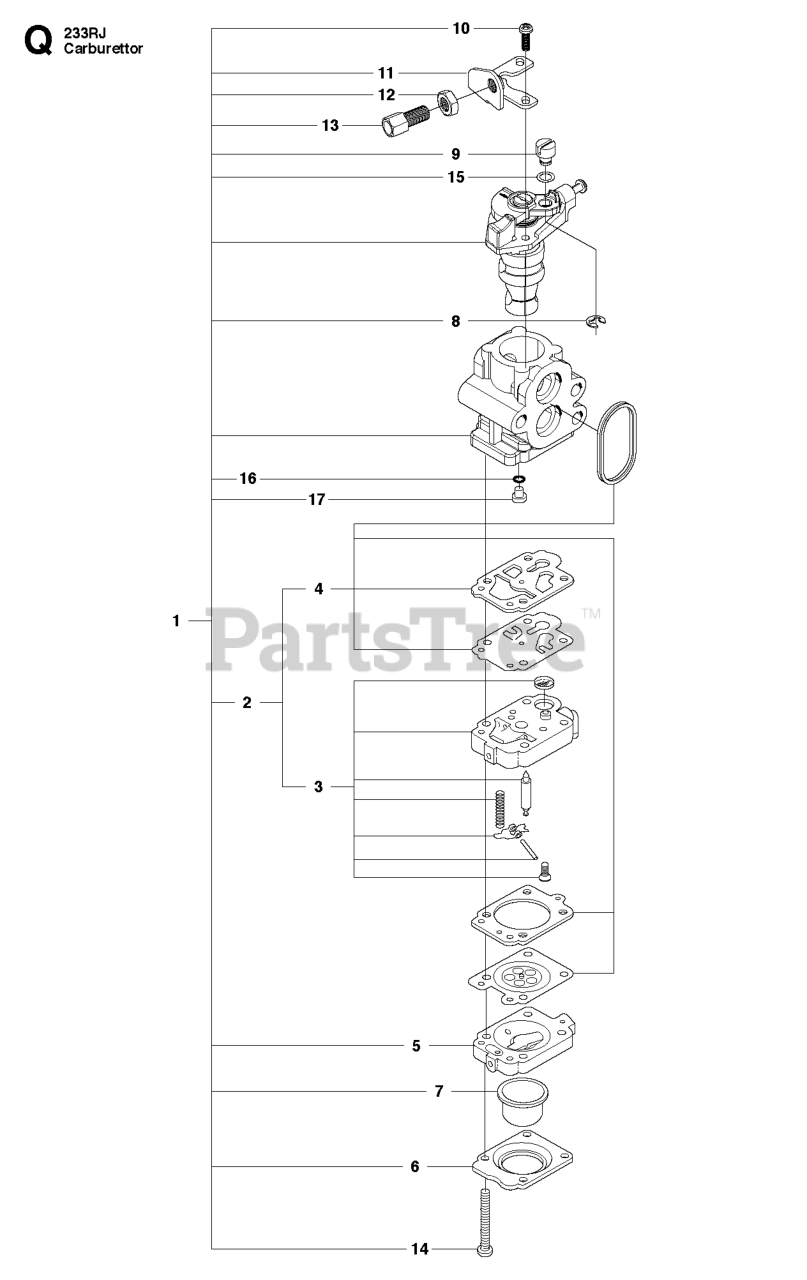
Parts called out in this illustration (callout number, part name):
4	GASKET KIT
5	BODY
7	PUMP
12	NUT
13	SCREW CABLE ADJUST
